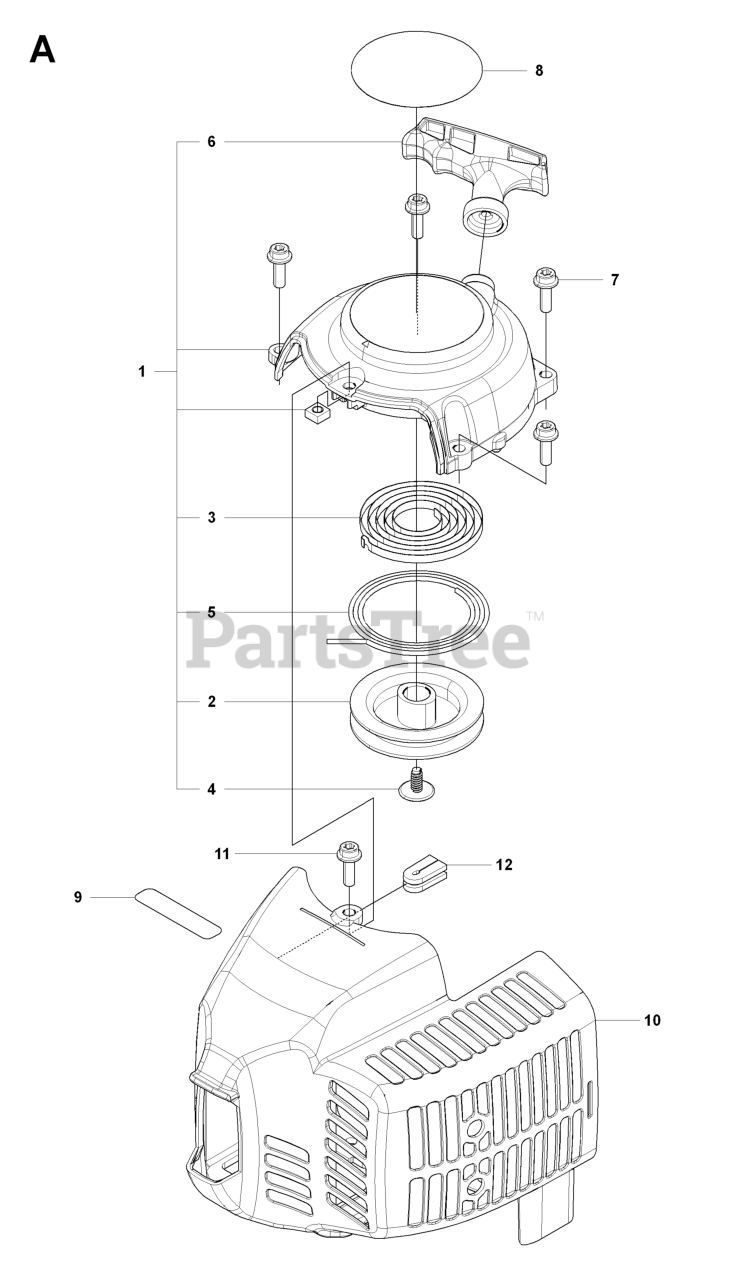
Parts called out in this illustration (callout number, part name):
1	RECOIL ASSY
4	SCREW
7	BOLT TORX
8	LABEL RECOIL
9	LABEL WARNING
10	COVER ENGINE
11	BOLT TORX
